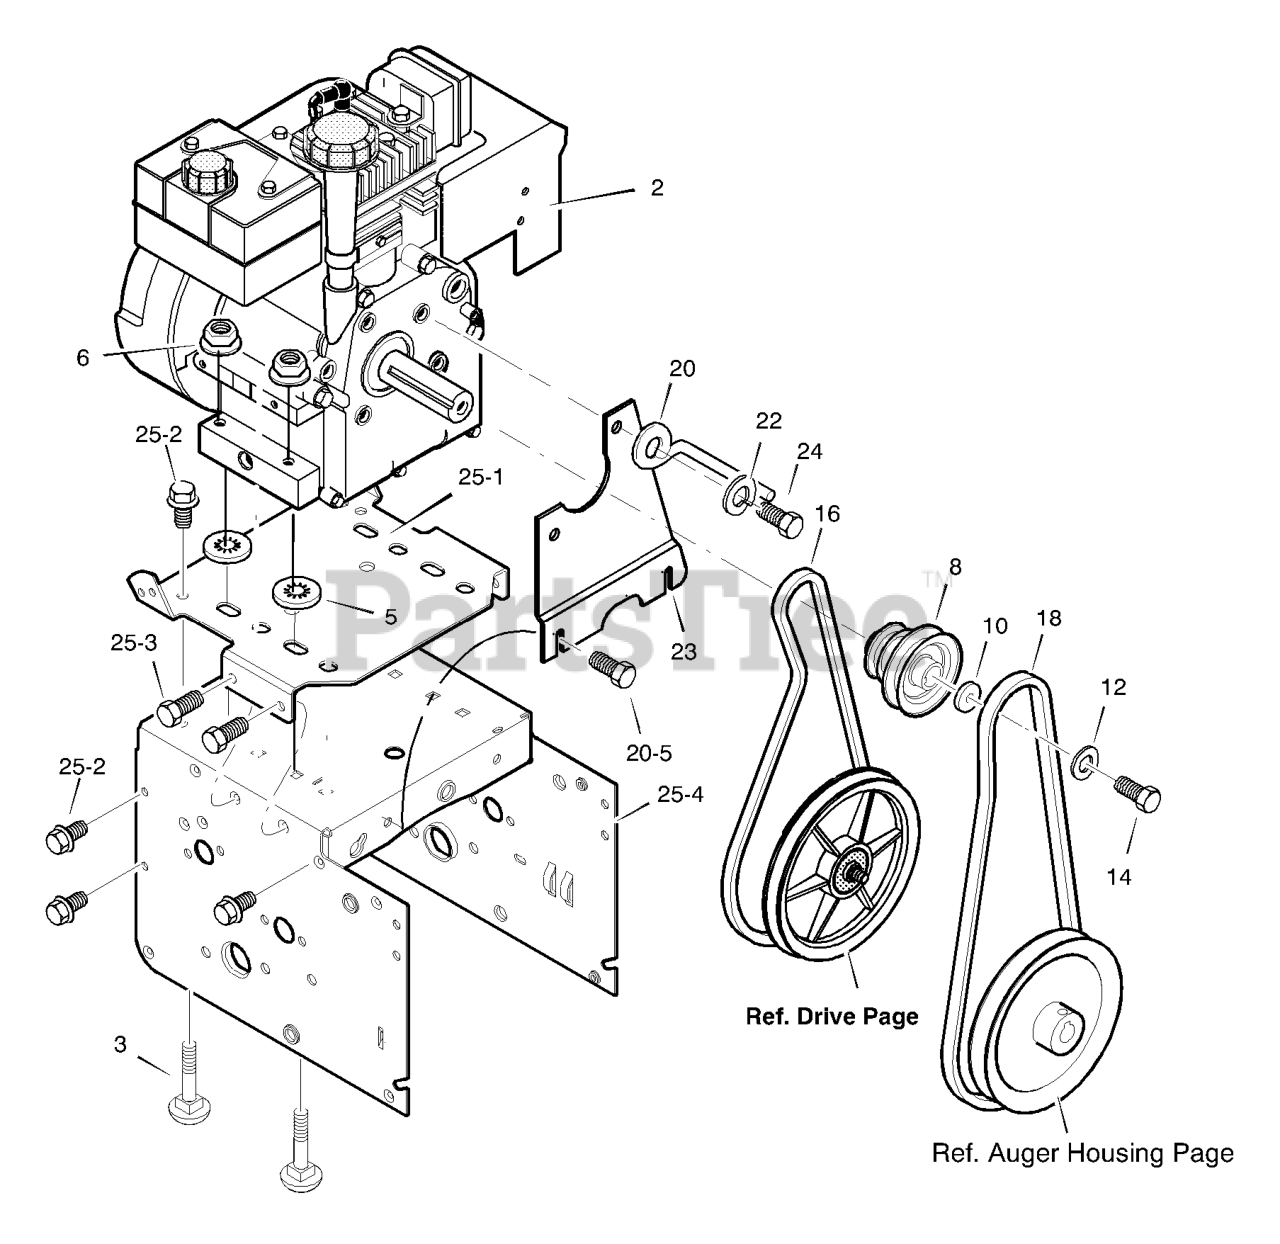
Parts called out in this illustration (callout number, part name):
2	ENGINE
3	BOLT, CARRIAGE 5/16-18
5	RETAINER, PUSH
6	NUT, HEX 5/16-18
8	PULLEY, ENGINE
10	WASHER
12	WASHER .38ID
14	SCREW, 3/8-24 x 1.00
16	BELT, V 3L 33.13LG
18	BELT, V 4L 38.1MF16" 5-10
20	GUIDE, BELT
22	WASHER, SPTLK .31X.58X.08
23	PLATE, ANTI VIBRATION
24	SCREW, 5/16-24 x 1.00
25	FRAME ASSEMBLY
25-1	PLATE, ENGINE MOUNT
25-2	SCREW, TAP 1/4-20 X .63
25-3	SCREW, TAP 5/16-18 X .50
25-4	FRAME, MOTOR BOX
